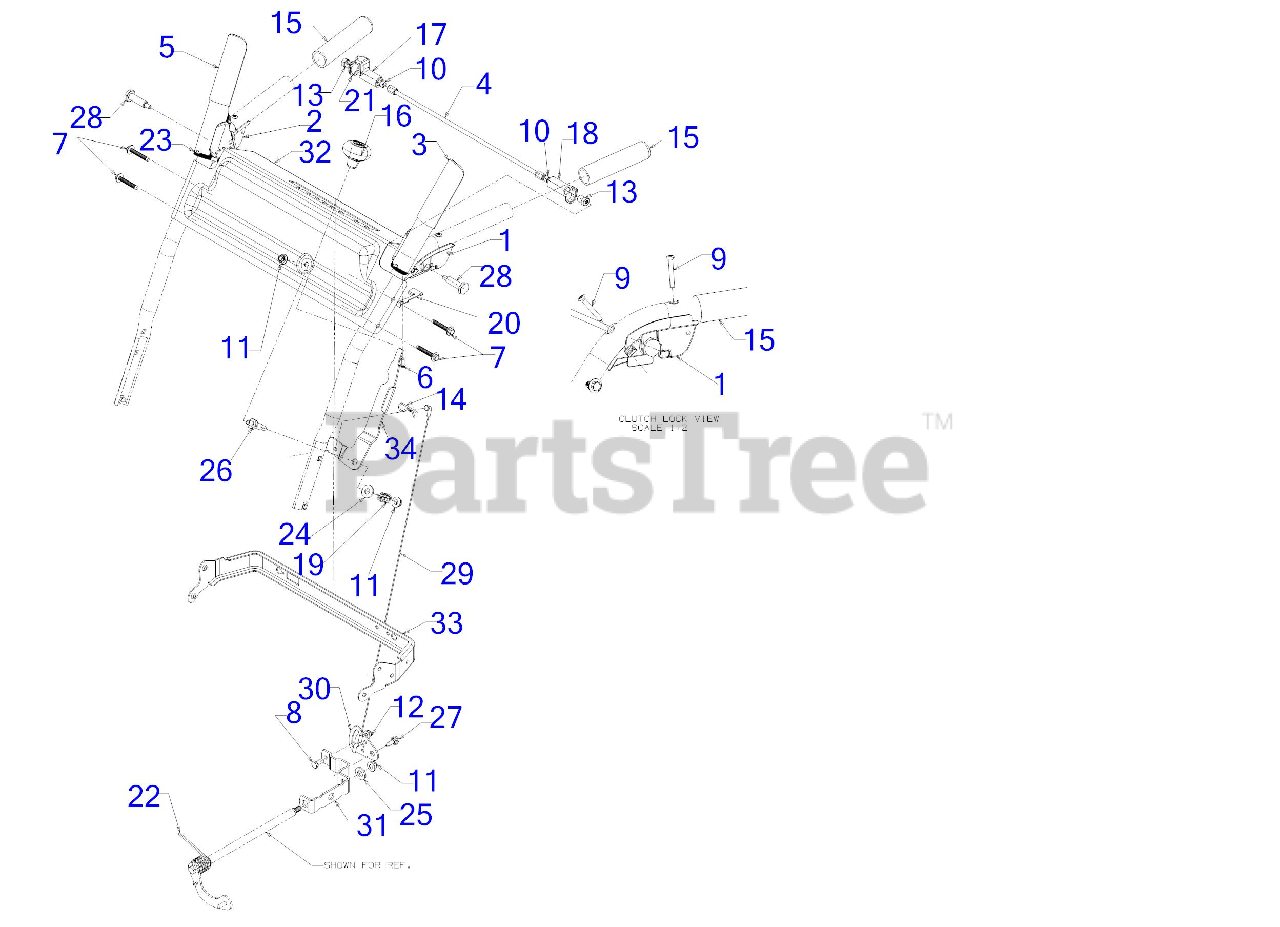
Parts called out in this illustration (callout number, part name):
1	CLUTCH LOCK HANDLE ASSEMBLY (LH)
2	CLUTCH LOCK HANDLE ASSEMBLY (RH)
3	HANDLE ASSEMBLY (LH)
4	PIVOT ROD
5	HANDLE ASSEMBLY (RH)
6	SCREW #8-16 x .50
7	SCREW 1/4-20 x 1.625
8	SCREW 1/4-20 x .620 GR5
9	SCREW #10-24 x 1.375
10	SCREW 1/4-20 x .50
11	FLANGE LOCK NUT 5/16-18
12	FLANGE LOCK NUT
13	HEX NUT W/PATCH
14	INTERNAL COTTER PIN
16	SHIFT KNOB
17	LOCK PLATE
18	CLUTCH LOCK CAM
19	COMPRESSION SPRING
20	CLUTCH SPRING
21	TORSION SPRING
22	TORSION SPRING
23	RUBBER BUMPER
24	FLAT WASHER .385X.870X.090
25	FLAT WASHER
26	SHOULDER BOLT
27	SHOULDER SCREW
28	SHOULDER SCREW .437 x 1.345 1/4-20
29	SPEED SELECTOR CABLE (STEEL)
30	PIVOT BRACKET
31	SHIFT SPEED BRACKET
